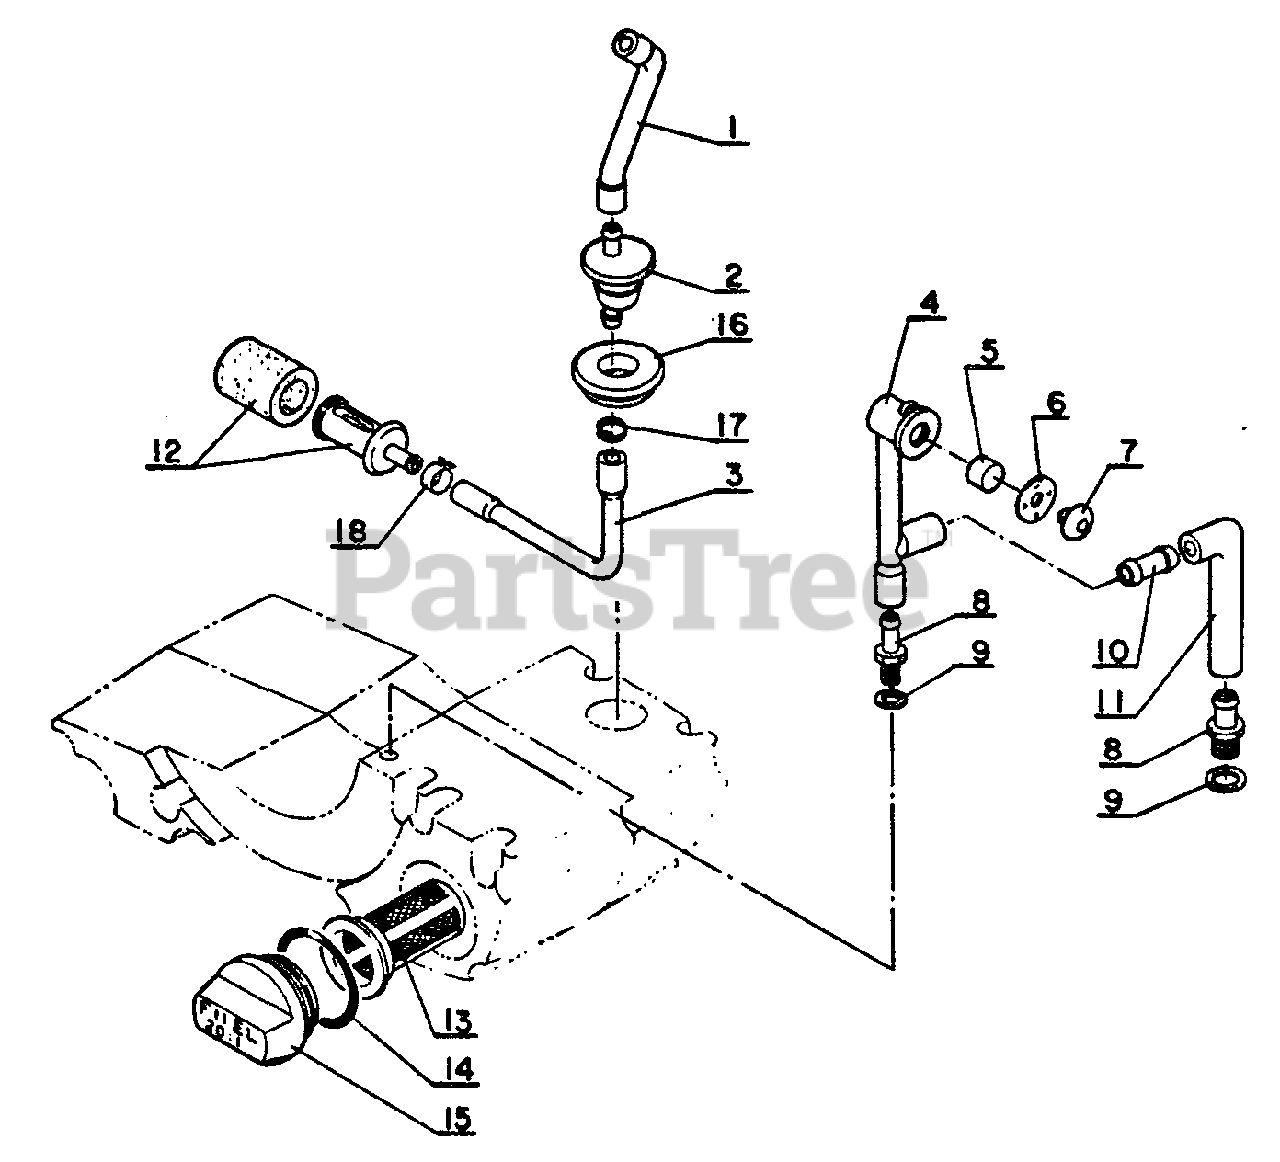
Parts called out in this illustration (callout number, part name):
1	PIPE, FUEL
2	CONNECTOR, PIPE
3	PIPE, FUEL - INNER
5	FILTER, AIR VALVE
6	HOLDER, VENT
7	VALVE, CHECK
8	FITTING, GREASE
9	PACKING, NIPPLE (B)
10	CONNECTOR, PIPE
11	CONNECTOR, PIPE
12	FILTER, FUEL
13	FILTER
14	O-RING 29
15	CAP
16	WASHER, SEAL
17	RETAINER, PIPE
18	CLIP
